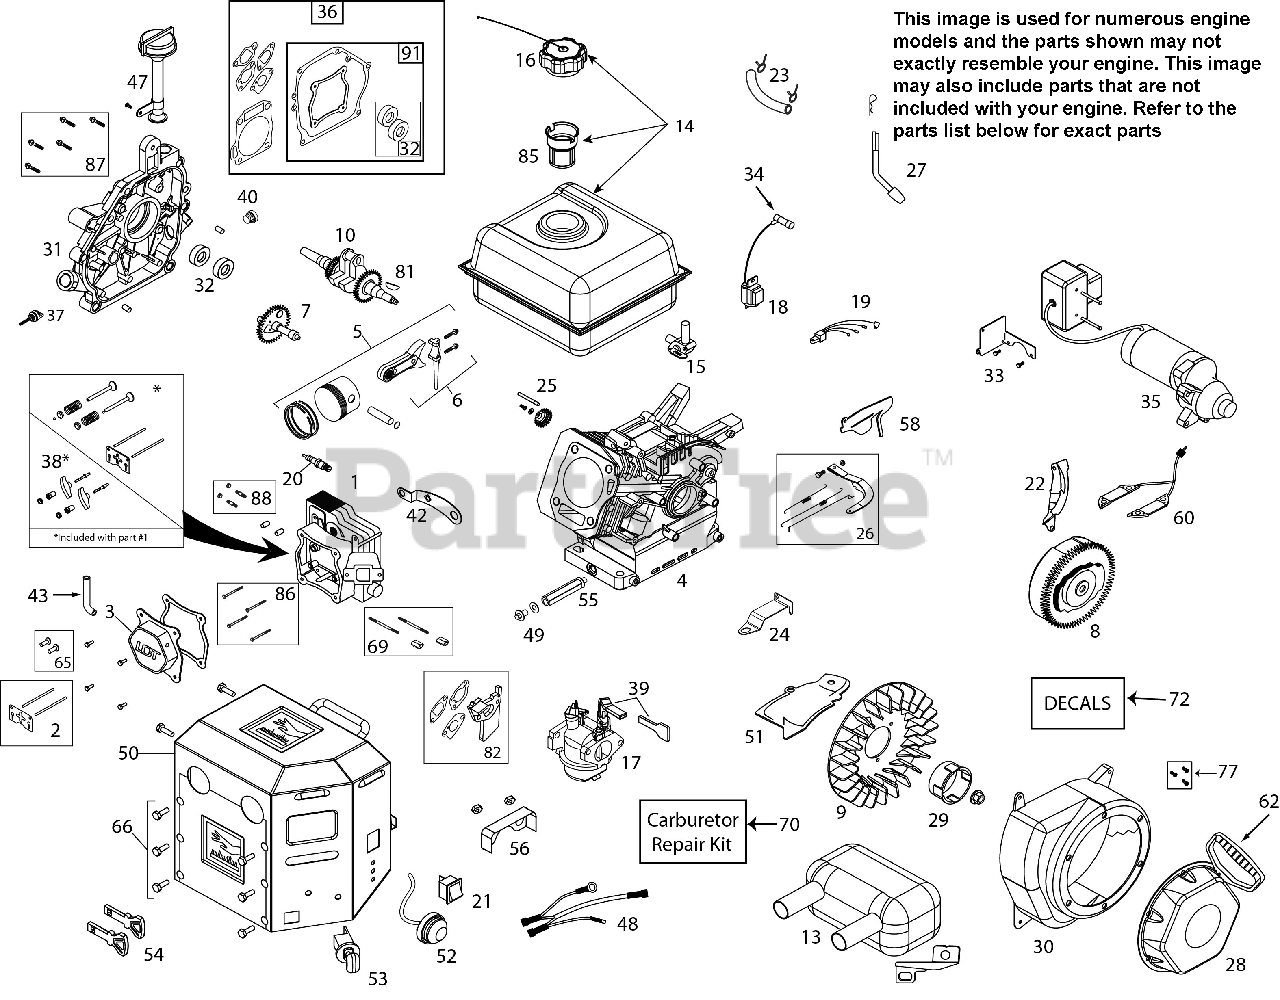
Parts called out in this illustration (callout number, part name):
1	CYLINDER HEAD ASSY (W/GASKET)
2	PUSH ROD & PLATE KIT (W/GASKT)
3	VALVE COVER (W/GASKET)
4	CYLINDER
5	PISTON & ROD ASSEMBLY
6	CONNECTING ROD ASSEMBLY
7	CAMSHAFT - MCR
8	FLYWHEEL - ELECTRIC START
9	COOLING FAN - FLYWHEEL
10	CRANKSHAFT (#18 KEYED)
13	MUFFLER ASSEMBLY
14	FUEL TANK (W/PLASTIC CAP)
15	FUEL TANK ON/OFF VALVE
16	CAP, FUEL TANK BLACK
17	CARBURETOR (W/GSKTS & SPACER)
18	IGNITION COIL KIT
18	IGNITION COIL (CDI) (STANDARD)
19	CDI MODULE - BLACK BOX
20	SPARK PLUG, ARIENS AX
21	ON/OFF SWITCH - ROCKER
22	SHIELD - FLYWHEEL ELECT START
23	FUEL HOSE KIT 1/4-318MM
24	SPEED CONTROL BRACKET (FIXED)
25	GOVERNOR GEAR ASSEMBLY
26	GOVERNOR ARM & LNK KIT 3600RPM
27	GOVERNOR ARM PADDLE
28	RECOIL STARTER ASSY RND-BLACK
29	STARTER CUP RND STYLE STARTER
30	BLOWER HOUSING (W/WELDNUT)
31	CRANKCASE COVER ASSY W/GASKET
32	OIL SEAL KIT(2 PCS 3/4" CRANK)
34	SPARK PLUG BOOT (W/MTL SHIELD)
35	230V ELECTRIC STARTER
35	STARTER SWITCH SCREWS
36	ENGINE GASKET KIT
37	SMALL BLACK OIL DIPSTICK
38	ROCKER ARM KIT (W/GASKET)
39	CHOKE CONTROL KNOB (RED)
40	NON-REMOVABLE PLASTIC PLUG
41	POLY PRE-FILTER P AIR CLEANER
42	CDI BOX MTG BRACKET
43	BREATHER TUBE
47	HIGH OIL-FILL TUBE/DIPSTICK
48	WIRE HARNESS
49	OIL DRAIN PLUG (W/WASHER)
50	HEATER BOX KIT
51	SHIELD - CYLINDER
52	PRIMER BULB WITH HOSE-SNOW
53	SAFETY KEY SWITCH (W/KEYS)
54	KEY, PUSH/PULL LCT (2/PACKAGE)
55	OIL DRAIN TUBE
56	CARBURETOR VAPOR SHIELD
57	CE COMPLIANT MUFFLER SHIELD
58	SHIELD - GOVERNOR LINKAGE
59	FUEL TANK SKIRT
60	CHARGING COIL (6-WATT AC)
61	FUEL CONTROL KNOB (RED)
62	STARTER GRIP
65	TAPPET KIT (SET OF 2)
69	CARBURETOR STUDS & COUPLNG KIT
70	CARBURETOR REPAIR KIT
72	STORMFORCE LABEL KIT
74	MUFFLER HEAT SHIELD COVER
77	RECOIL BOLT KIT
78	BREATHER TUBE BRACKET
79	CARBURETOR COVER
81	WOODRUFF FLYWHEEL KEY 5-PACK
82	CARBURETOR SPACER
85	FUEL TANK STRAINER
86	HEAD BLT KIT 136-179-208-254CC
87	CC COVER BLT KIT 179-208-254CC
88	MUFFLER MTG STUD KIT
91	CRANKCASE GASKET KIT 208GEN1&2
9999	HARDWARE KIT (4 M6X10 FLG BLT)
9999	HIGH ALT JET-208CC L10-1 CARB
